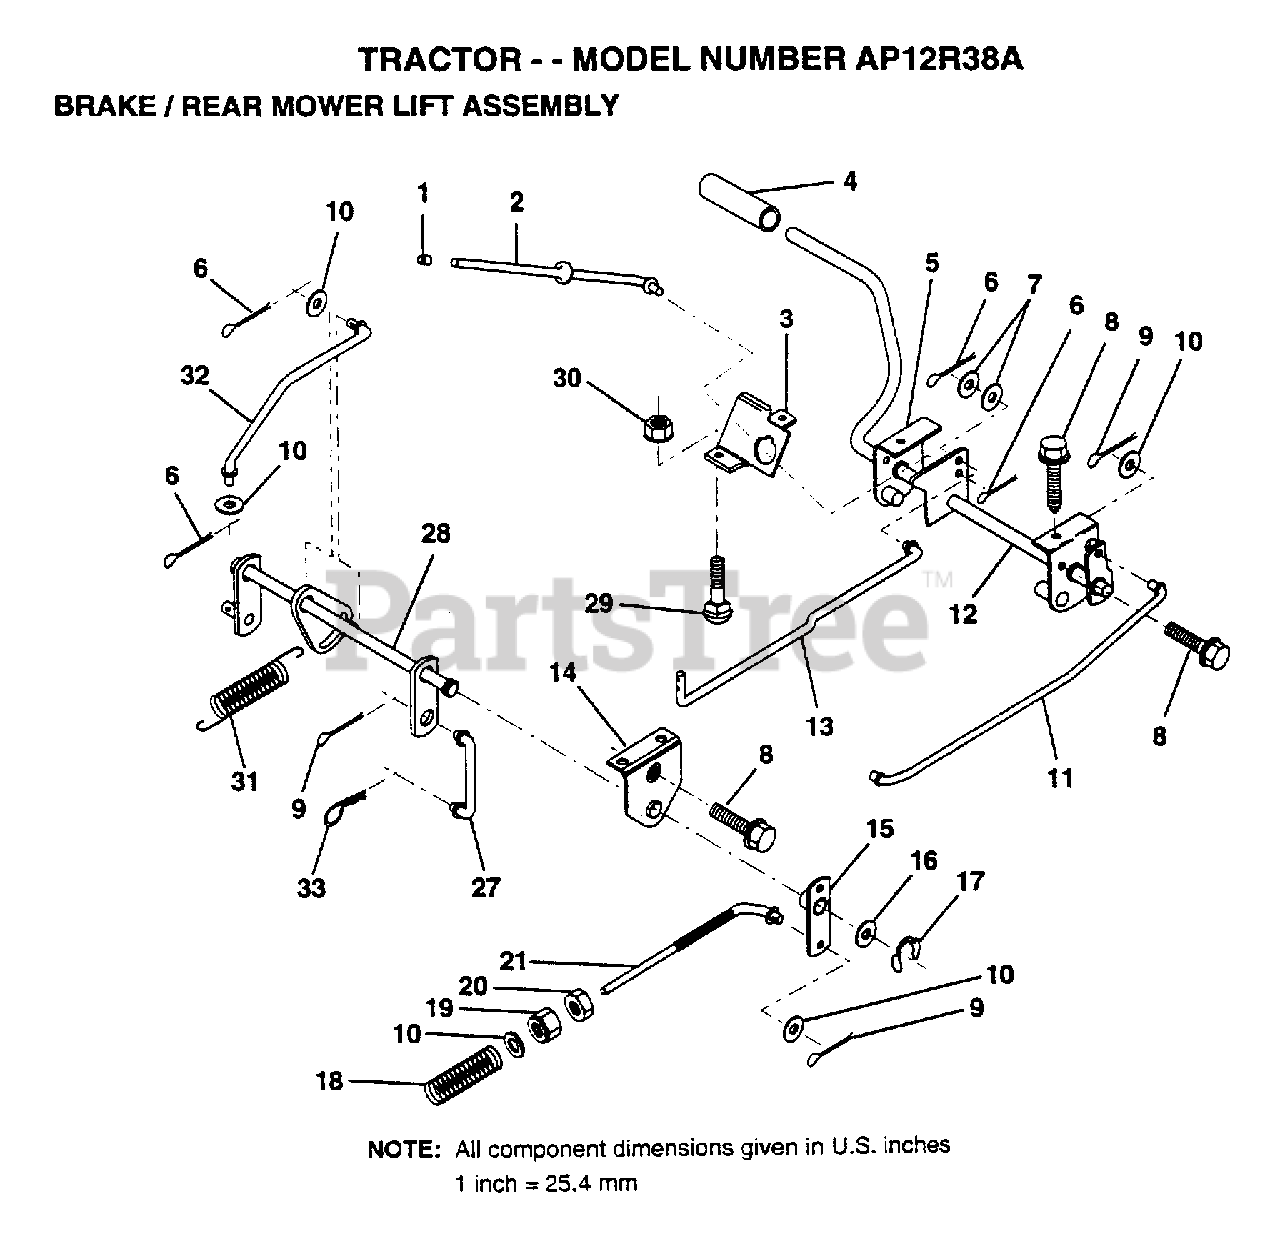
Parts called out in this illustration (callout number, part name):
1	PLUNGER CAP T
2	"ROD,PARK BRAKE"
3	"BRKT,PARK BRAKE"
4	PEDAL COVER T
5	BRK ASM CLUT LH
7	WASHER
8	SCREW LT
9	COTTER PIN
10	WASHER
11	"ROD,FRT BRAKE"
12	PEDAL ASM CLU/BRK
13	"ROD,CLUTCH"
14	"BRKT,LIFT SHAFT"
15	PVT BRAKE ARM ASM
16	WASHER T
17	KLIP RING
18	SPRING ROD LT
19	NUT
21	ROD.BRAKE.HYDRO
27	LINK LIFT REAR LR
28	LIFT.ASM.REAR.LR
31	COUNTER SPRING
32	LINK LIFT LEVER
